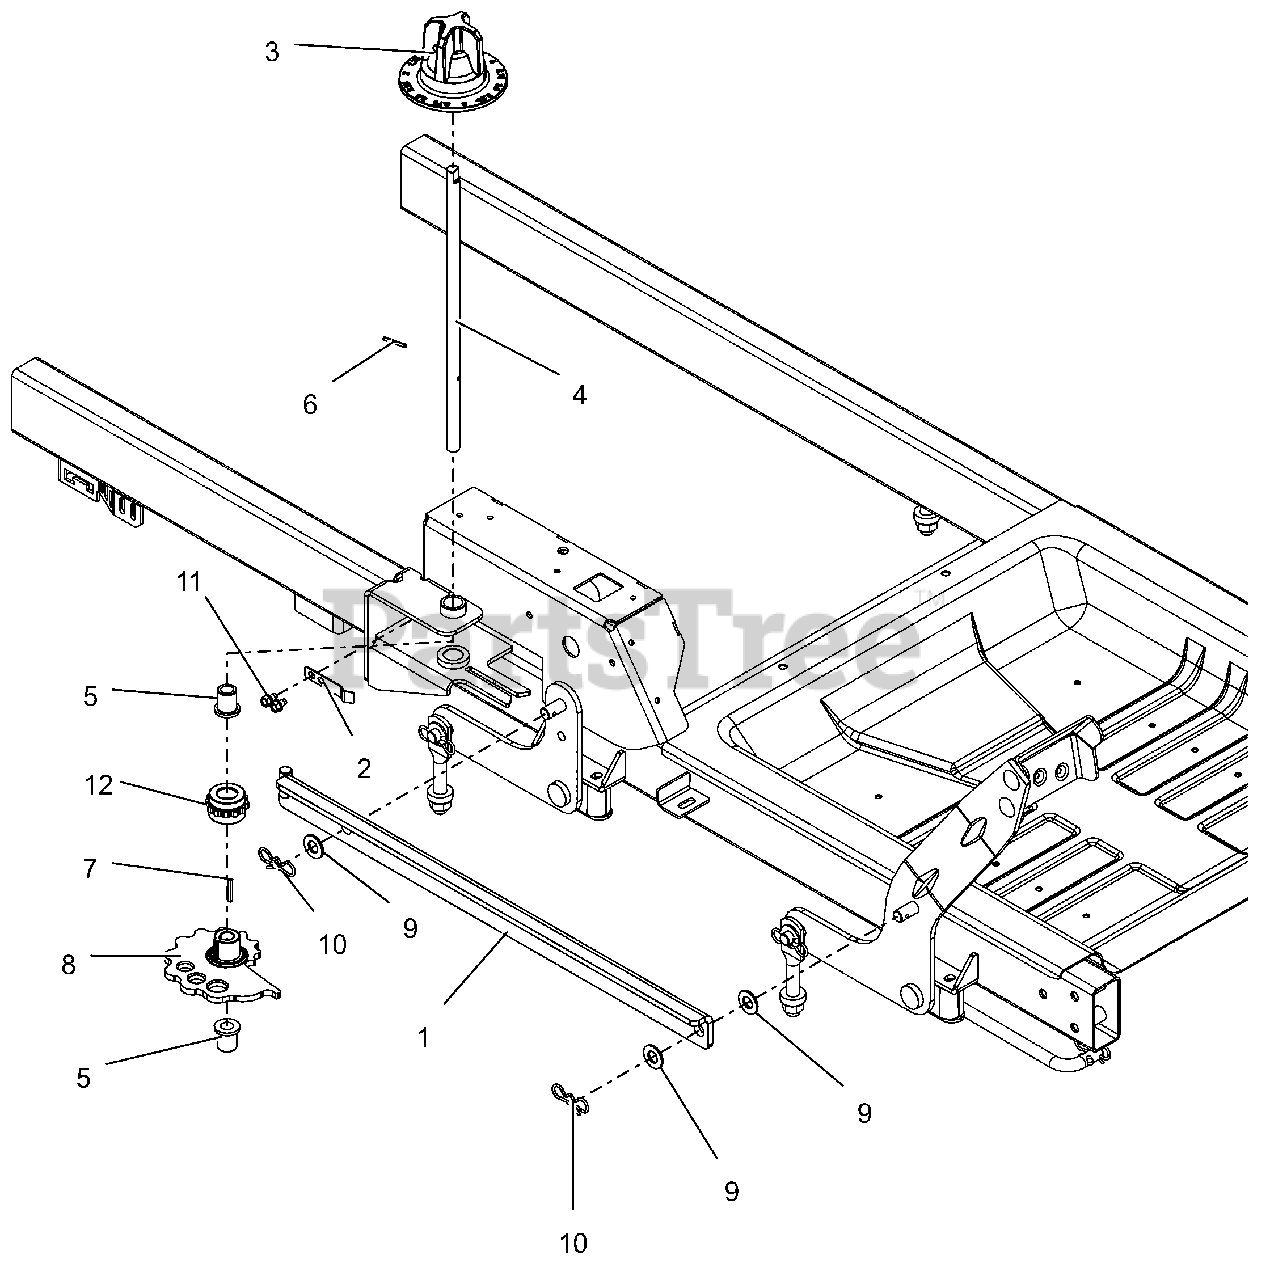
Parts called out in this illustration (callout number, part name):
1	WLDMT, HOC LINK
2	ARM, HOC DETENT
3	KNOB, HOC DIAL
4	SHAFT, HOC CAM
5	BSHG-FLG, .503X.750X.875X1.00
6	PIN-ROLL .125X1.00
7	KEY, 1/8 X 1/8 X 1.0
8	CAM, HOC (PM)
9	WSHR-FL-NYL .518X1.000X.080
10	PIN, BOWTIE .091X1.875 ZCC
11	SCR,TAP .25-20X.375 HWH TR ZCC
12	GEAR, HOC INDEX
